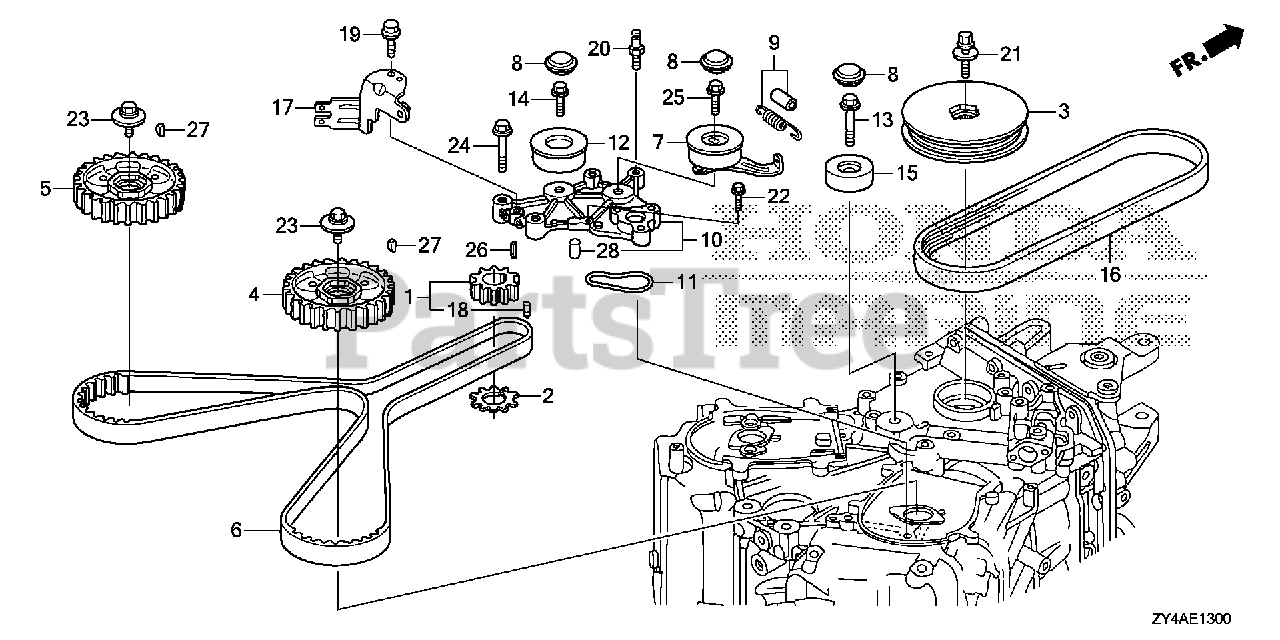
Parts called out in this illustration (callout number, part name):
1	PULLEY, TIMING BELT DRIVE
2	PLATE, TIMING BELT GUIDE
3	PULLEY, CRANKSHAFT
4	PULLEY, R. TIMING BELT DRIVEN
5	PULLEY, L. TIMING BELT DRIVEN
6	BELT, TIMING (197YU26 GB-323)
7	TENSIONER, TIMING BELT
8	CAP, TIMING BELT TENSIONER
9	SPRING, TIMING BELT ADJUSTING
10	BASE, TIMING BELT TENSIONER *NH8* (DARK GRAY)
11	O-RING, TIMING BELT TENSIONER BASE
12	IDLER, TIMING BELT (KOYO SEIKO)
13	BOLT, IDLER
14	BOLT, TIMING BELT IDLER A
15	IDLER B, TIMING BELT
16	BELT, ALTERNATOR (6PK745 M-180)
17	BRACKET, CONNECTOR D
18	PIN, VERTICAL SHAFT
19	BOLT, FLANGE (6X14) (CT200)
20	BOLT, TIMING BELT ADJUSTING SPRING
21	BOLT-WASHER (16X49)
22	BOLT, FLANGE (6X22)
23	BOLT-WASHER (12X35)
24	BOLT, FLANGE (10X40)
25	BOLT, FLANGE (10X43)
26	KEY (4.5X24)
27	KEY, SPECIAL
28	PIN, DOWEL (6X10)
